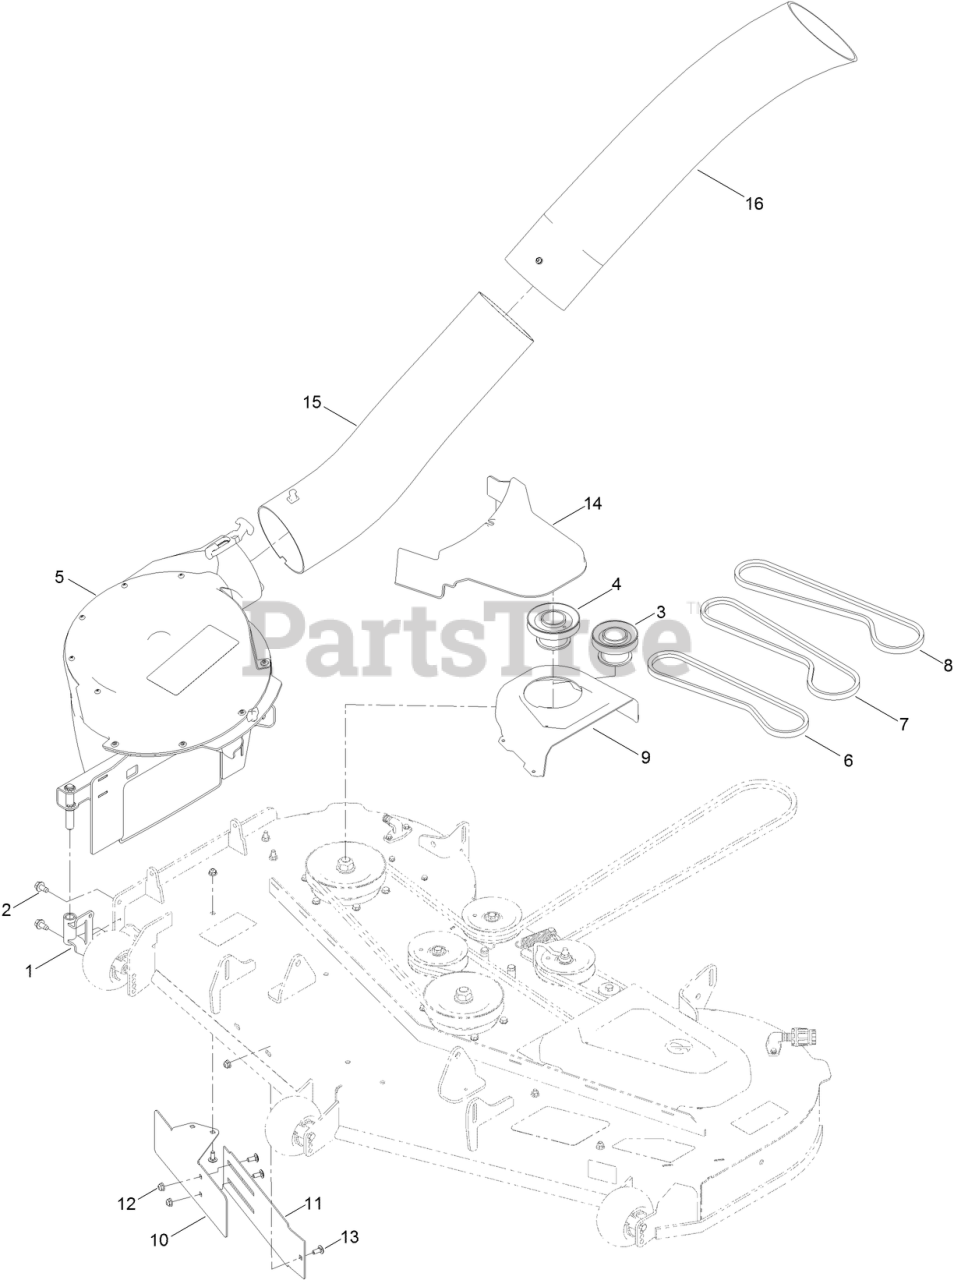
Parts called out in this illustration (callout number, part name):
1	PIVOT-BLOWER
2	SCREW-HWH
3	PULLEY-BAGGER
4	PULLEY-BAGGER
5	Blower Housing Assembly
6	BELT-V
7	BELT-V
8	BELT-V
9	COVER-BELT, RH
10	BAFFLE-OUTER
11	BAFFLE-INNER
12	NUT-HF
13	BOLT-CARR
14	COVER-BAGGER, POWERED
15	Lower Tube ASM
16	Upper Tube ASM
